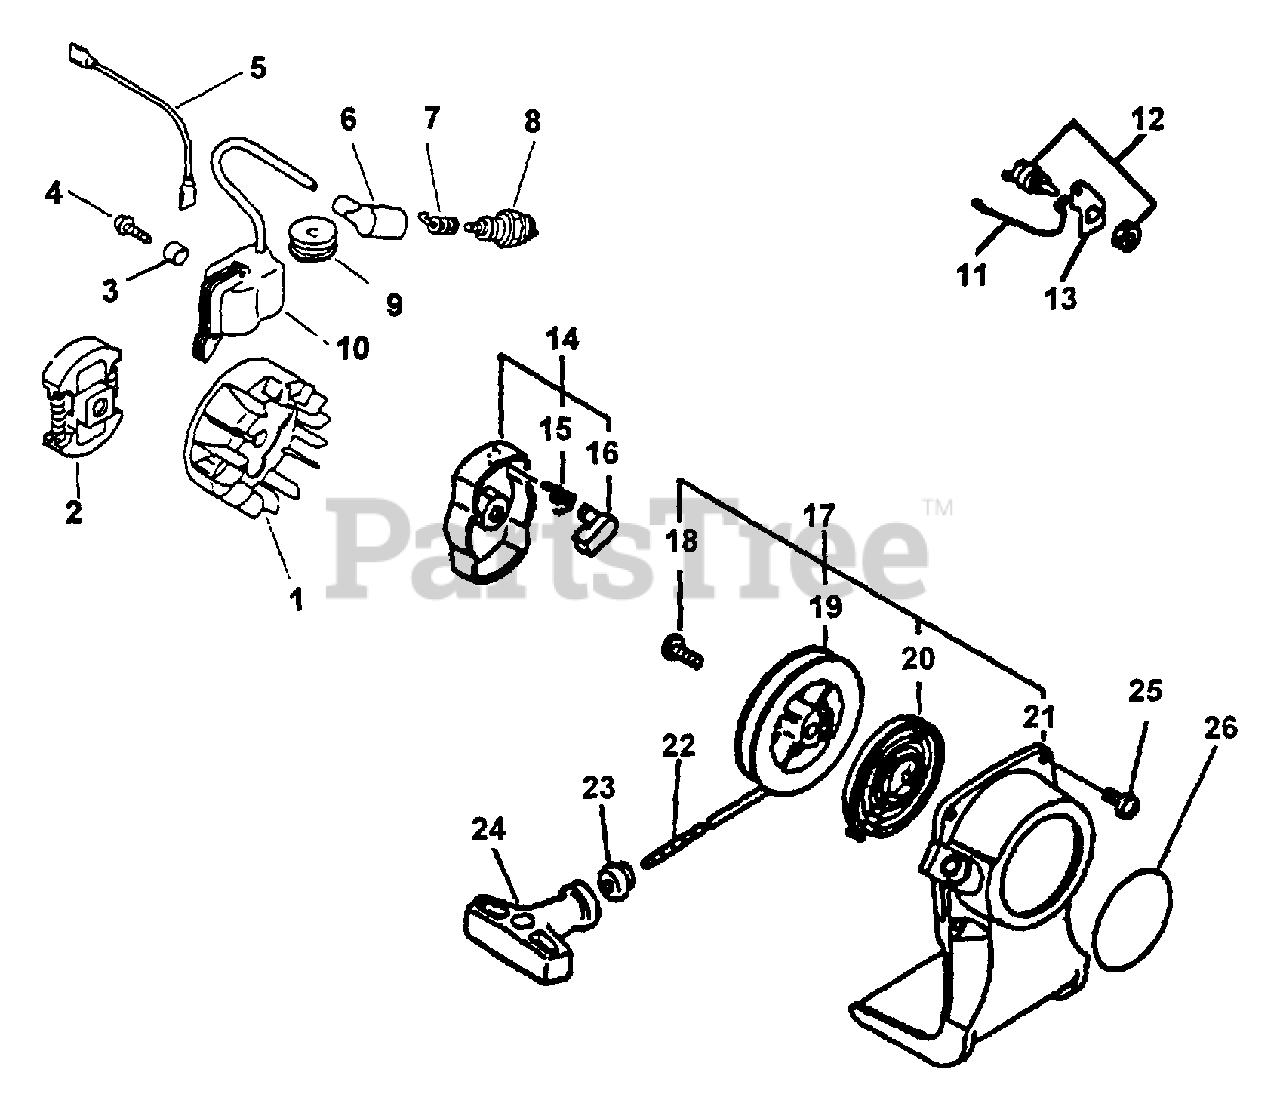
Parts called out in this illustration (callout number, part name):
1	FLYWHEEL
2	CLUTCH ASSY
4	SCREW 4×22
5	LEAD - GROUND
6	CAP, SPARK PLUG
7	TERMINAL, SPARK PLUG
8	SPARK PLUG - BPM7A
10	COIL, IGNITION
11	LEAD - GROUND
12	SWITCH, ON-OFF
13	BRACKET, SWITCH
14	PAWL ASSY, STARTER
15	SPRING, RETURN
16	PAWL, STARTER - BLACK
17	STARTER ASSY
18	SCREW
19	REEL, ROPE
20	SPRING, RECOIL
21	CASE, RECOIL STARTER
22	ROPE, STARTER
23	GUIDE, ROPE
24	GRIP, STARTER
25	BOLT 4×16
26	LABEL, ECHO
